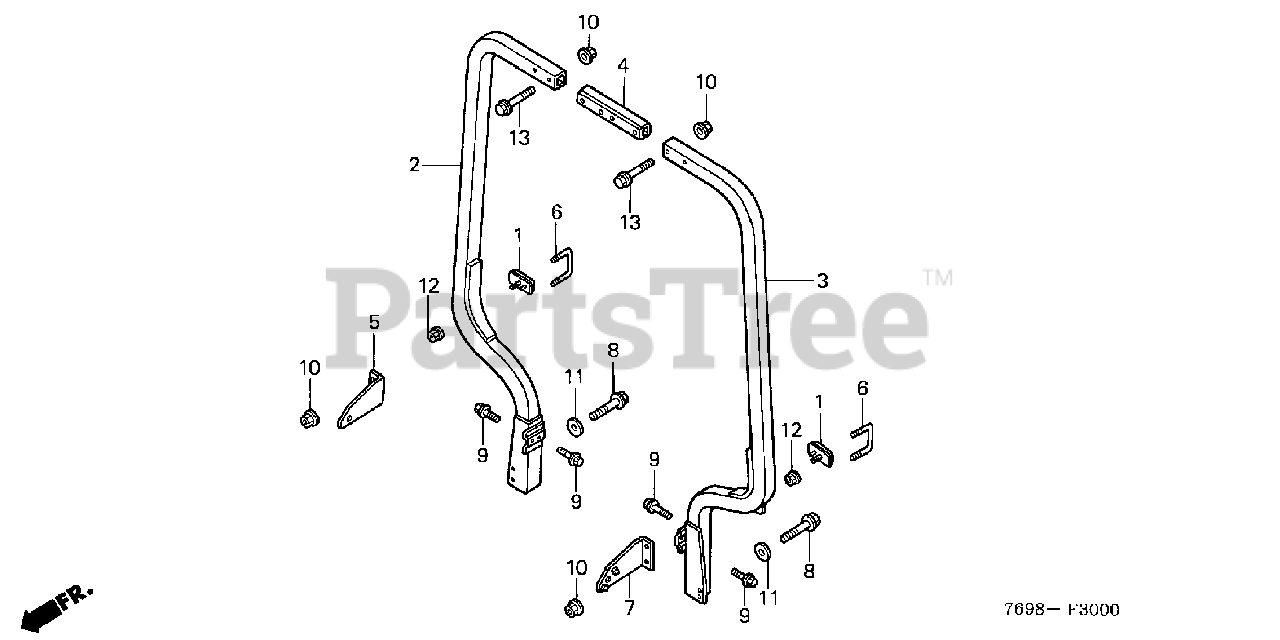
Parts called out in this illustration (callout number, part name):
1	REFLECTOR, REFLEX
2	ROPS., R. *NH1* (BLACK)
3	ROPS., L. *NH1* (BLACK)
4	JOINT, ROLL OVER PROTECTIVE STRUCTURE
5	PLATE, R. SEAT BELT
6	U-BOLT (10X74)
7	PLATE, L. SEAT BELT
8	BOLT, FLANGE (10X30)
9	BOLT, HEX. (10X25)
10	NUT, U (10MM)
11	WASHER (10.3X25)
12	NUT, FLANGE (5MM)
13	BOLT, FLANGE (10X60)
